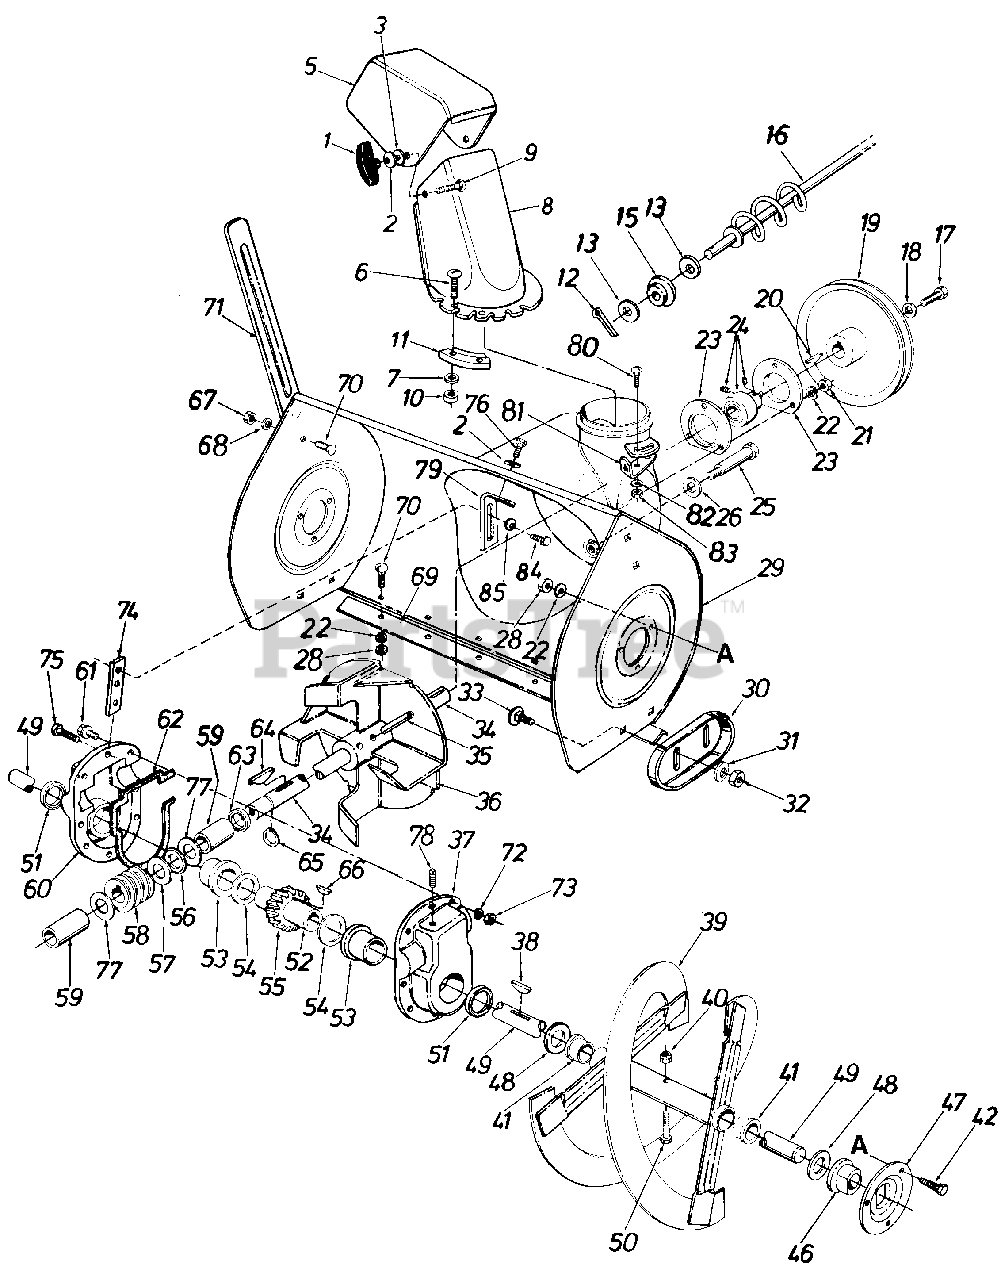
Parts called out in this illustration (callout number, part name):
1	Hand Knob Ass'y.
2	Bell-Wash. .345 I.D. x .88 O.D. x .060
3	Fl. Wash. .312 I.D. x 1.125 O.D. x .125
5	Top Chute
6	Truss Mach. Scr. 1/4-20 x .75"
7	Fl-Wash. 1/4" I.D.
8	Chute
9	Carr. Bolt 5/16-18 x 1.00" Lg.
10	Hex Cent L-Nut 1/2-20 Thd.
11	Chute Flange Keeper
12	Cotter Pin
13	Fl-Wash. .385" I.D. x .62"
15	Bushing
16	Chute Crank Ass'y.
17	Hex L-Scr. 5/16-18 x .88" Lg.
18	Bell-Wash. .345 I.D. x .88
19	V-Pulley .875 I.D. x 10.12
20	#9 Hi-Pro Key 3/16 x 3/4" Dia.
21	Hex Nut 5/16-18 Thd.
22	L-Wash. 5/16" I.D.
23	Bearing Hsg. Self Aligning Brg.
24	Self Aligning Brg. .875 I.D.
25	Stud 3/8-16 x 2.75" Lg.
26	Bell-Wash. .400 I.D. x .88 O.D. x .060
28	Hex Nut 5/16-18 Thd.
29	Blower Hsg. Ass'y.
30	Slide Shoe
31	Bell-Wash. .400 I.D. x .88 O.D. x .060
32	Hex Jam Nut 3/8-16 Thd.
33	Carr. Bolt 3/8-16 x .62" Lg.
34	Blower Axle
35	Spring Pin Spiral 5/16" Dia. x 1.75" Lg.
38	#91 Woodruff Key 1/4" x 3/4" Dia.
39	Spiral Ass'y. L.H.
40	Hex Ins. L-Nut 5/16-18 Thd.
41	Plastic Bushing
42	Hex Sems Scr. 5/16-18 x .75"
46	Flange Brg. w/Flats 1.0" I.D.
47	Bearing Hsg. Spiral Hsg.
48	Fl-Wash. 1.06 I.D. x 1.75" O.D. x .100
49	Spiral Axle
50	Hex Bolt 5/16-18 x 1.75" Lg.
51	Oil Seal 1.50" I.D.
52	Worm Gear Shaft
53	Flange Brg. 1.503 I.D.
54	Fl-Wash. 1.5 I.D. x 2.0 O.D.
55	Double Threaded Worm Gear
56	Thrust Brg. .88 I.D. x 1.44 O.D. x .078
57	Fl-Wash. .88 I.D. x 1.40 O.D.
58	Doubie Threaded Worm L.H.
59	Sleeve Brg. .875 I.D.
60	Complete Gear Hsg. Half R.H.
61	Hex Bolt 5/16-18 x 1.0" Lg.
62	Gasket
63	Oil Seal .875" I.D.
64	#9 Hi-Pro Key 3/16 x 3/4" Dia.
65	Snap Ring .875" Dia.
66	#91 Woodruff Key 1/4 X 3/4" Dia.
67	Hex Nut 5/16-18 Thd.
68	L-Wash. 5/16" I.D.
70	Carr. Bolt 5/16-18 x .62" Lg.
71	Drift Cutter
72	Wave Wash. 5/16" I.D.
73	Hex Ins. L-Nut 5/16-18 Thd.
74	Gear Hsg. Support Plate
75	Hex Bolt 5/16-18 x 1.25"
76	Hex Wash. Hd. Self-Tap Scr. 5/16-18 x .75" Lg.
77	Fl-Wash. .88 I.D. x 1.40 O.D.
78	Filler Plug
80	Carr. Bolt 5/16-18 x .75" Lg.
82	Bell-Wash. .345 I.D. x .88"
83	Hex Nut 5/16-18 Thd.
84	Hex Bolt 1/4-28 x .75" Lg.
85	Bell-Wash. .28" I.D. x .75" O.D.
